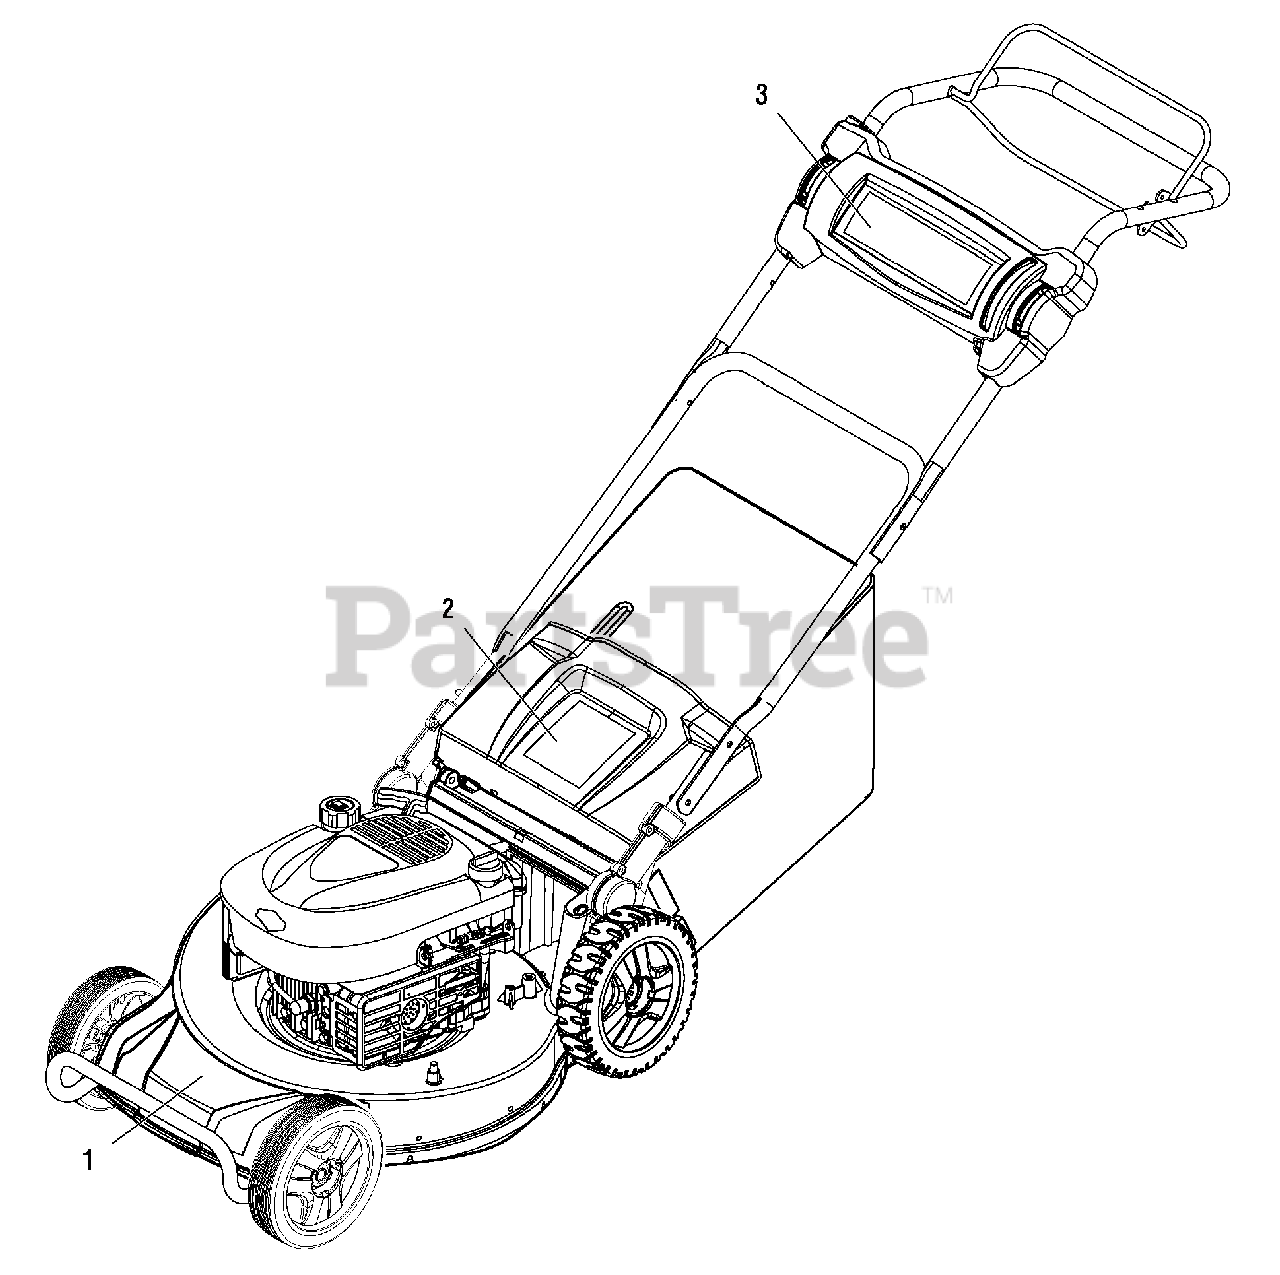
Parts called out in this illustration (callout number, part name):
1	DECAL, Logo, Deck
2	DECAL, Safety
3	DECAL, Logo, Cover
